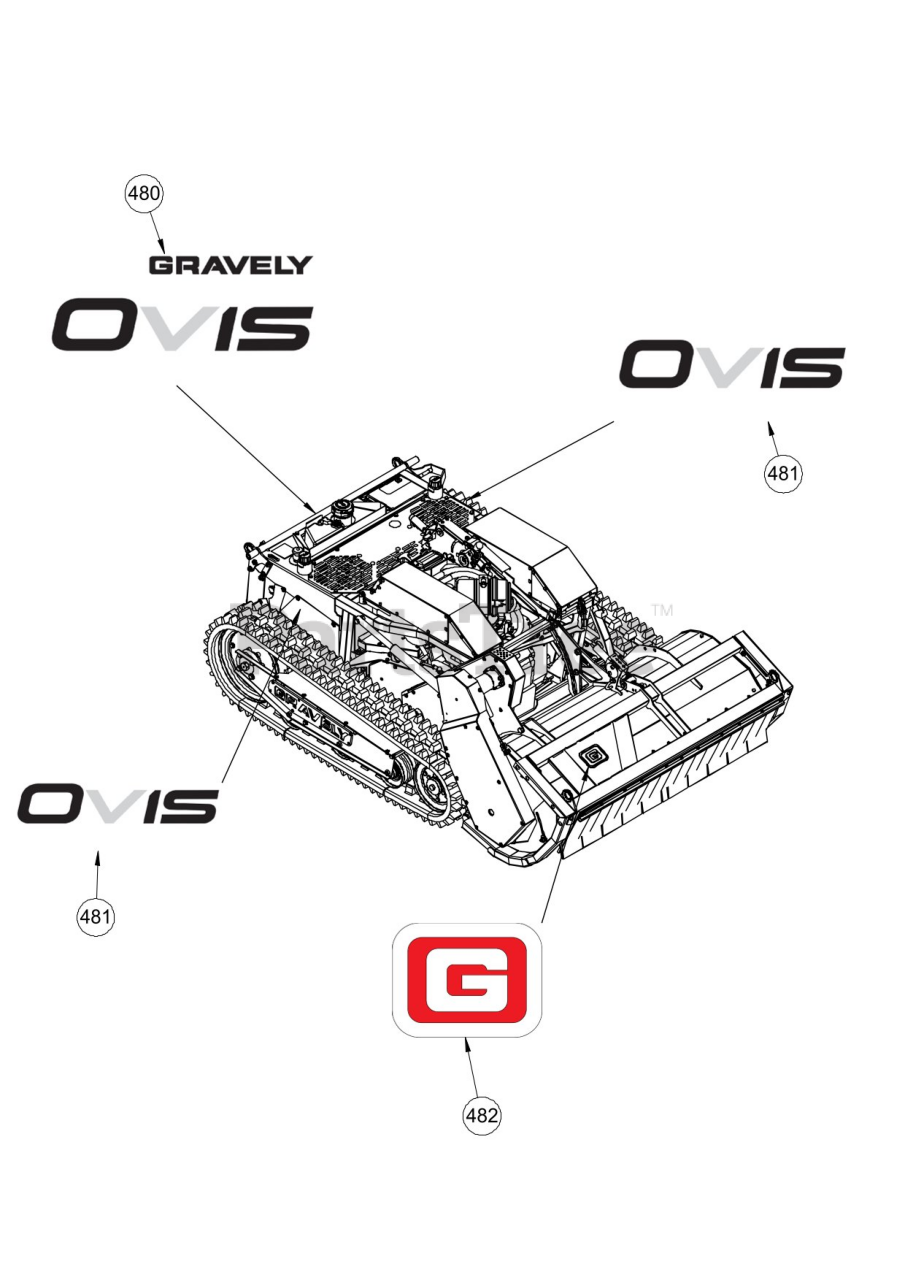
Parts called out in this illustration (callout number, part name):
480	Decal, OVIS 40 RC Rear
481	Decal, OVIS 40 RC Side
482	DECAL, GRAVELY BRAND
